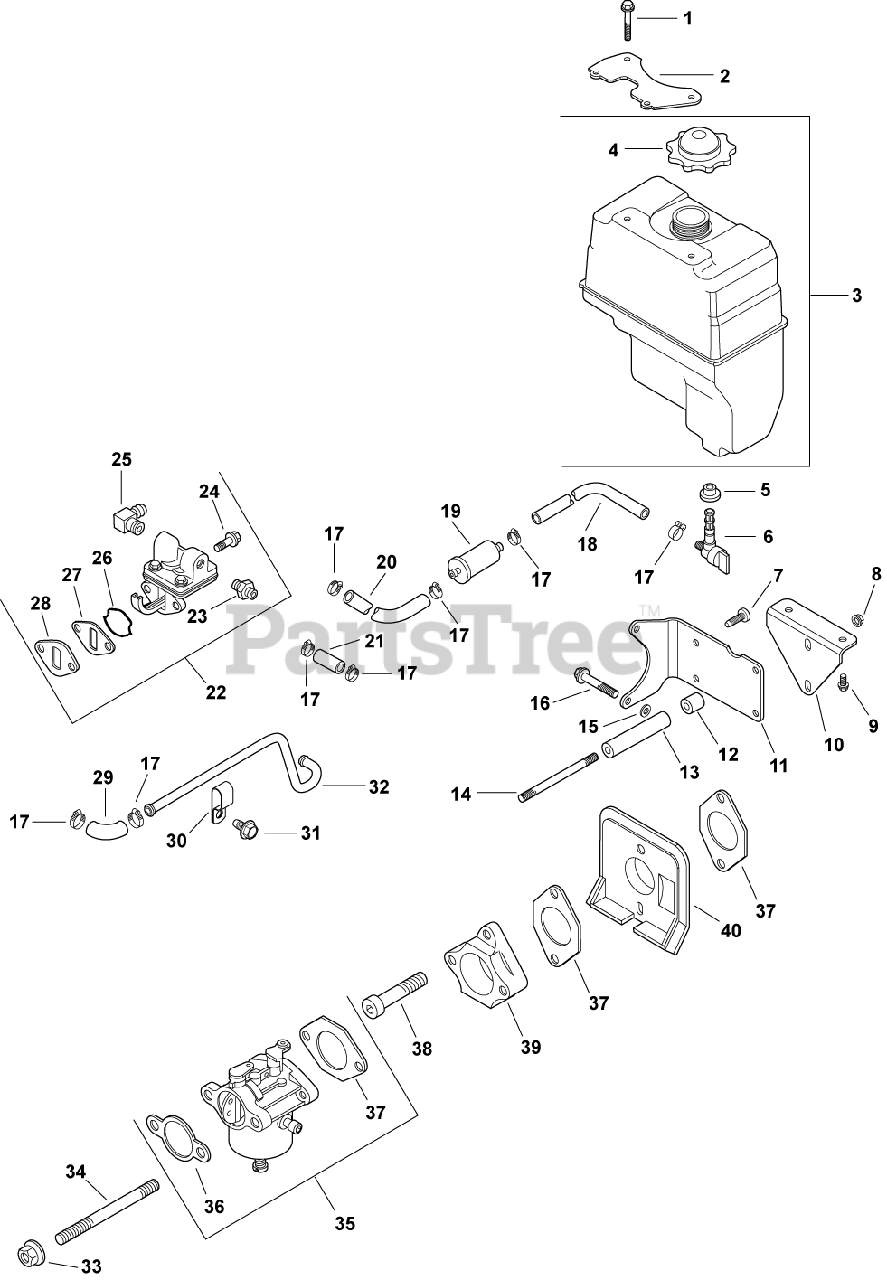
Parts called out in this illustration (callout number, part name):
1	SCREW,FLG THD FRM M6X1.0X25-(#25086395S)
2	BRACKET, FUEL TANK
3	KIT, FUEL TANK
4	CAP, FUEL TANK
5	BUSHING, FUEL TANK
6	VALVE, FUEL SHUT-OFF
7	SCREW, LBD SKT M6x1.0x20-(#25086403S)
8	NUT, FLG M8X1.25
9	SCREW, FLG M6X1.0X12
11	BRACKET, FUEL TANK
13	SPACER, FUEL TANK
14	STUD, M8X1.25X133-USE 25 755 54-S
15	WASHER, FLAT 11/32"
16	SCREW, FLG M8X1.25X50
17	CLAMP, HOSE (KM)-USE 25 237 31-S
18	LINE, FLEXIBLE FUEL
19	FILTR,FUEL 75 MICRON (GRAVTY FEED)
20	LINE, FUEL 2" PUMP-FILTER
21	LINE - DISCONTINUED
22	KIT, FUEL PUMP
23	KIT, STRAIGHT FITTING
24	SCREW,FLG THD FRM M6X1.0X20-(#25086396S)
25	CONNECTOR, 90 DEG. HOSE
26	O-RING, FUEL PUMP
27	SPACER, FUEL PUMP
28	GASKET, FUEL PUMP
29	HOSE, FUEL LOW-PERMEATION
30	CLIP, TUBE & WIRING (KM)
31	SCREW, FLG THD FRM M5X.8X10
32	LINE, FUEL - DISCONTINUED
33	NUT, FLG M6X1.0
34	STUD,M6X1.0X116
35	KIT, CARBURETOR
36	GASKET, AIR CLEANER BASE
37	GASKET, CARBURETOR
38	SCREW, SKT CAP M6X1.0X35
39	ADAPTER, CARBURETOR
40	DEFLECTOR, HEAT
